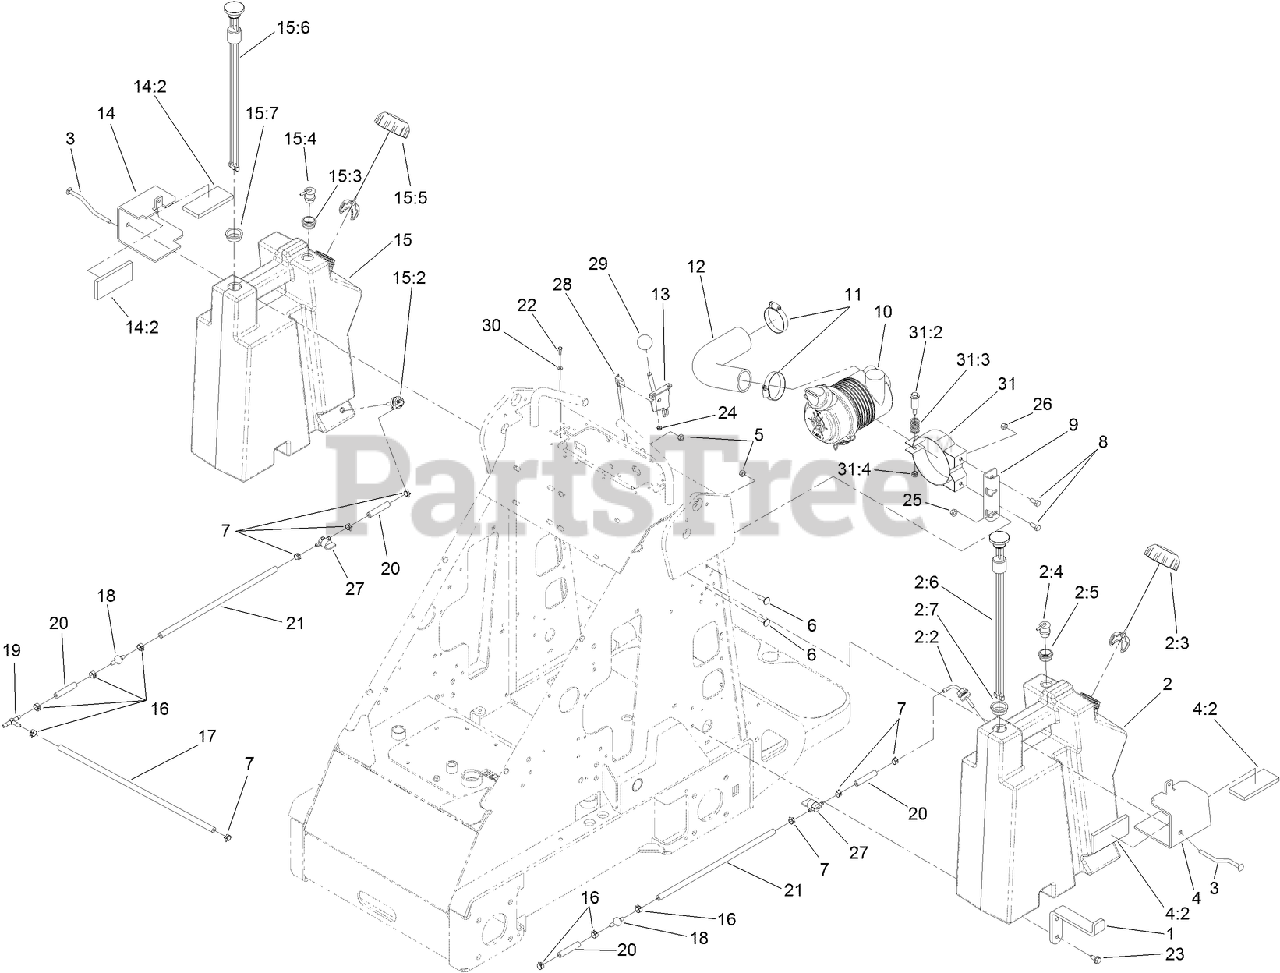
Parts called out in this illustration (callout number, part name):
1	MOUNT-TANK, BOTTOM
2	LH FUEL TANK ASM
2:2	FITTING-FUEL, BULKHEAD
2:3	CAP-FUEL
2:4	VALVE-ROLLOVER
2:5	GROMMET
2:6	GAUGE-LEVEL, FUEL
2:7	GROMMET
3	BOLT-MOUNT
4	LH TANK MOUNT ASM
4:2	PAD-FOAM
5	NUT-HEX, SIDE DEFORM
6	BOLT-CARR
7	CLAMP-HOSE
8	SCREW-HH
9	MOUNT-CLEANER, AIR
10	AIR CLEANER ASM
11	CLAMP-HOSE
12	HOSE-AIR
13	LEVER-CONTROL
14	RH TANK MOUNT ASM
14:2	PAD-FOAM
15	RH FUEL TANK ASM
15:2	FITTING-FUEL, BULKHEAD
15:3	CAP-FUEL
15:4	VALVE-ROLLOVER
15:5	GROMMET
15:6	GAUGE-LEVEL, FUEL
15:7	GROMMET
16	CLAMP-HOSE
17	HOSE-FUEL
18	VALVE-CHECK, FUEL
19	FITTING-TEE, BARBED
20	HOSE-FUEL
21	HOSE-FUEL
23	SCREW-HWHTF
24	NUT-KEPS
25	NUT-HF
26	NUT-LOCK, NI
27	VALVE-FUEL
28	CABLE-CONTROL
30	WASHER-FLAT
31	AIR CLEANER MOUNTING BAND ASM
31:3	SPRING
31:4	NUT
